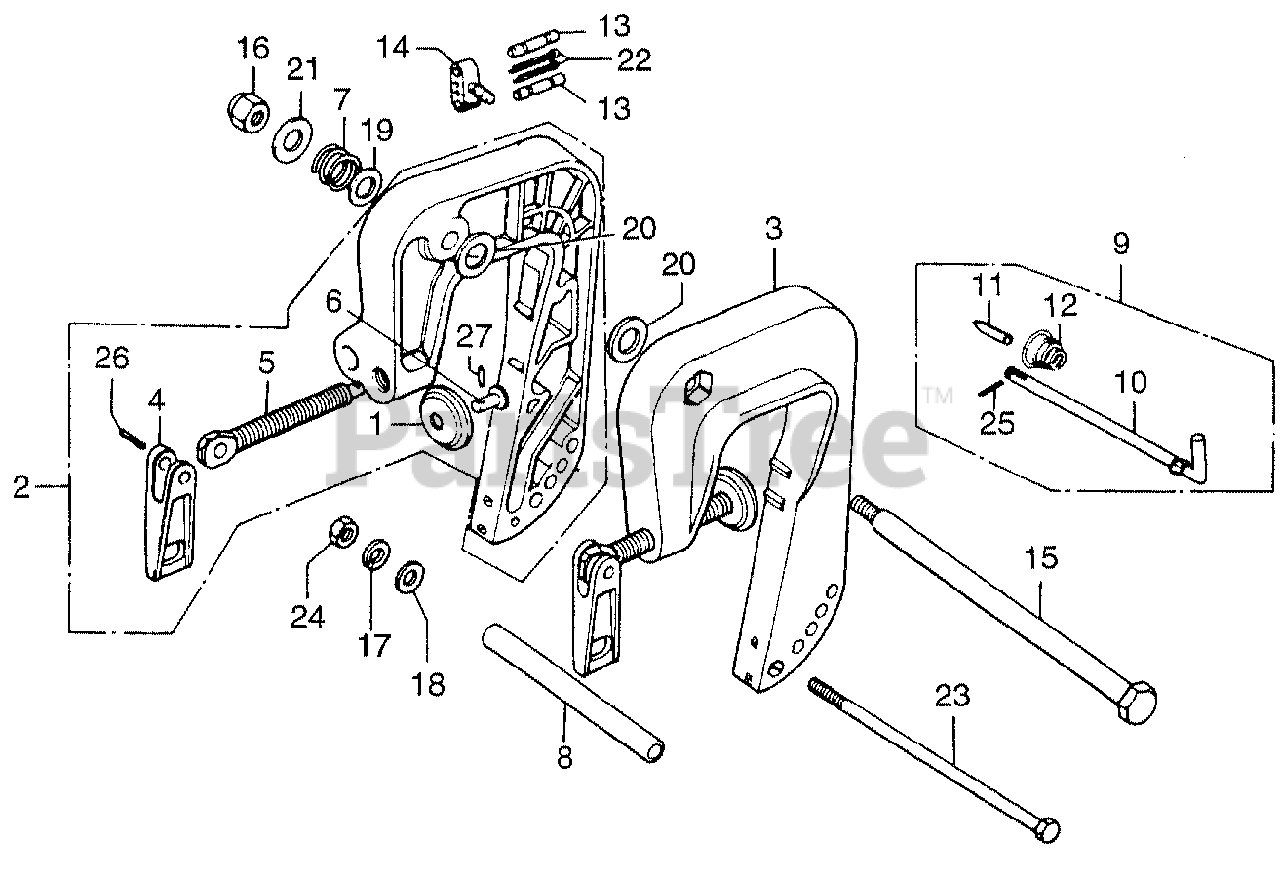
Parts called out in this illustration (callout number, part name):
1	PLATE, PUSH
2	BRACKET, R. STERN *PB1* (DARK BLUE) (NOT AVAILABLE)
3	BRACKET, L. STERN *PB1* (DARK BLUE) (NOT AVAILABLE)
4	GRIP, CLAMP *PB1* (DARK BLUE) (NOT AVAILABLE)
5	SCREW, CLAMP
6	PIN (6X13) (NOT AVAILABLE)
7	SPRING, TILT
8	COLLAR, DISTANCE (6MM)
9	ROD, ADJUSTING (N/A: SEE COMPONENTS)
10	ROD, ADJUSTING (NOT AVAILABLE)
11	STOPPER, ROD
12	SPRING, ADJUSTING ROD
13	PIN, SHEAR
14	HOLDER, PARTS
15	BOLT, TILTING
16	NUT, SELF-LOCK (8MM)
17	WASHER, SPRING (6MM)
18	WASHER, PLAIN (6MM)
19	WASHER, PLAIN (10MM)
20	WASHER (10MM)
21	WASHER (8MM)
22	PIN, COTTER (3MM)
23	BOLT, HEX. (6X160)
24	NUT, HEX. (6MM)
25	PIN, SPRING (2X8)
26	PIN, SPRING (4X14)
27	ROLLER (2.5X9.8) (NOT AVAILABLE)
